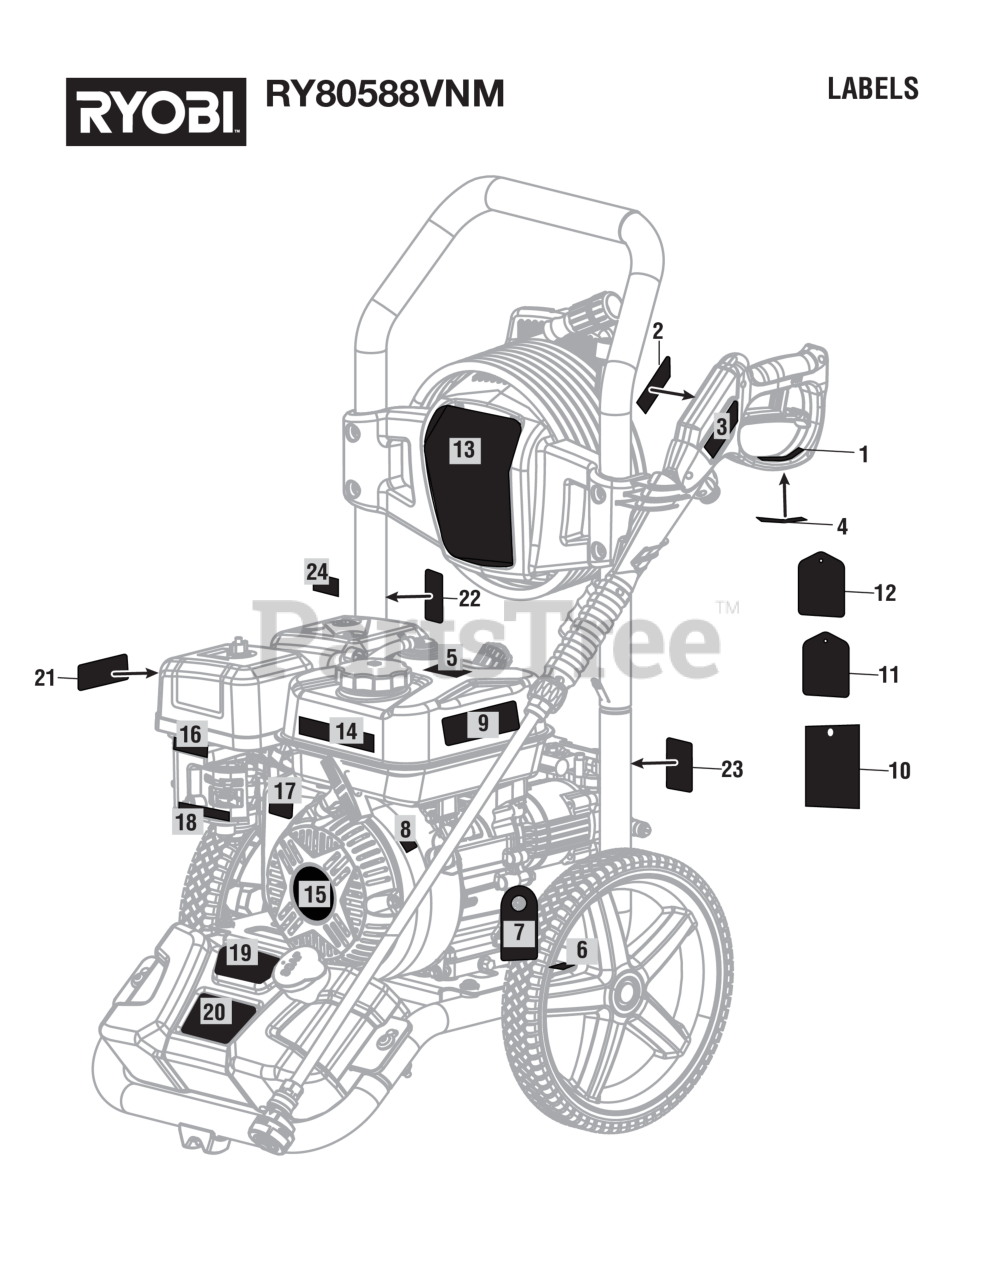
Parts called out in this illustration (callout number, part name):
1	Label (Trigger Handle Warning, French & Spanish)
2	LABEL, TRIGGER HANDLE LOGO
3	Trigger Handle Warning Label (English)
4	Trigger Handle Data Label
5	No E85 Label
6	Oil Fill Location Label
7	Label (Oil Dipstick Hangtag)
8	Engine Switch Label
9	Danger Label
10	Danger Hangtag
11	Nozzle Hangtag
12	Quick Start Hangtag
13	Performance Panel Label
14	Inquires Label (Ryobi)
15	Recoil Logo Label
16	Choke Label
17	Choke/Fuel Valve Label
18	Fuel Valve Label
19	Soap Tank Label
20	Soap Tank Logo Label
21	Hot Surface and
22	UL Fire Warning Label Spark Arrestor)
23	Warning Label
24	EMC ICES-2/NMB-2 Label (Canada)
